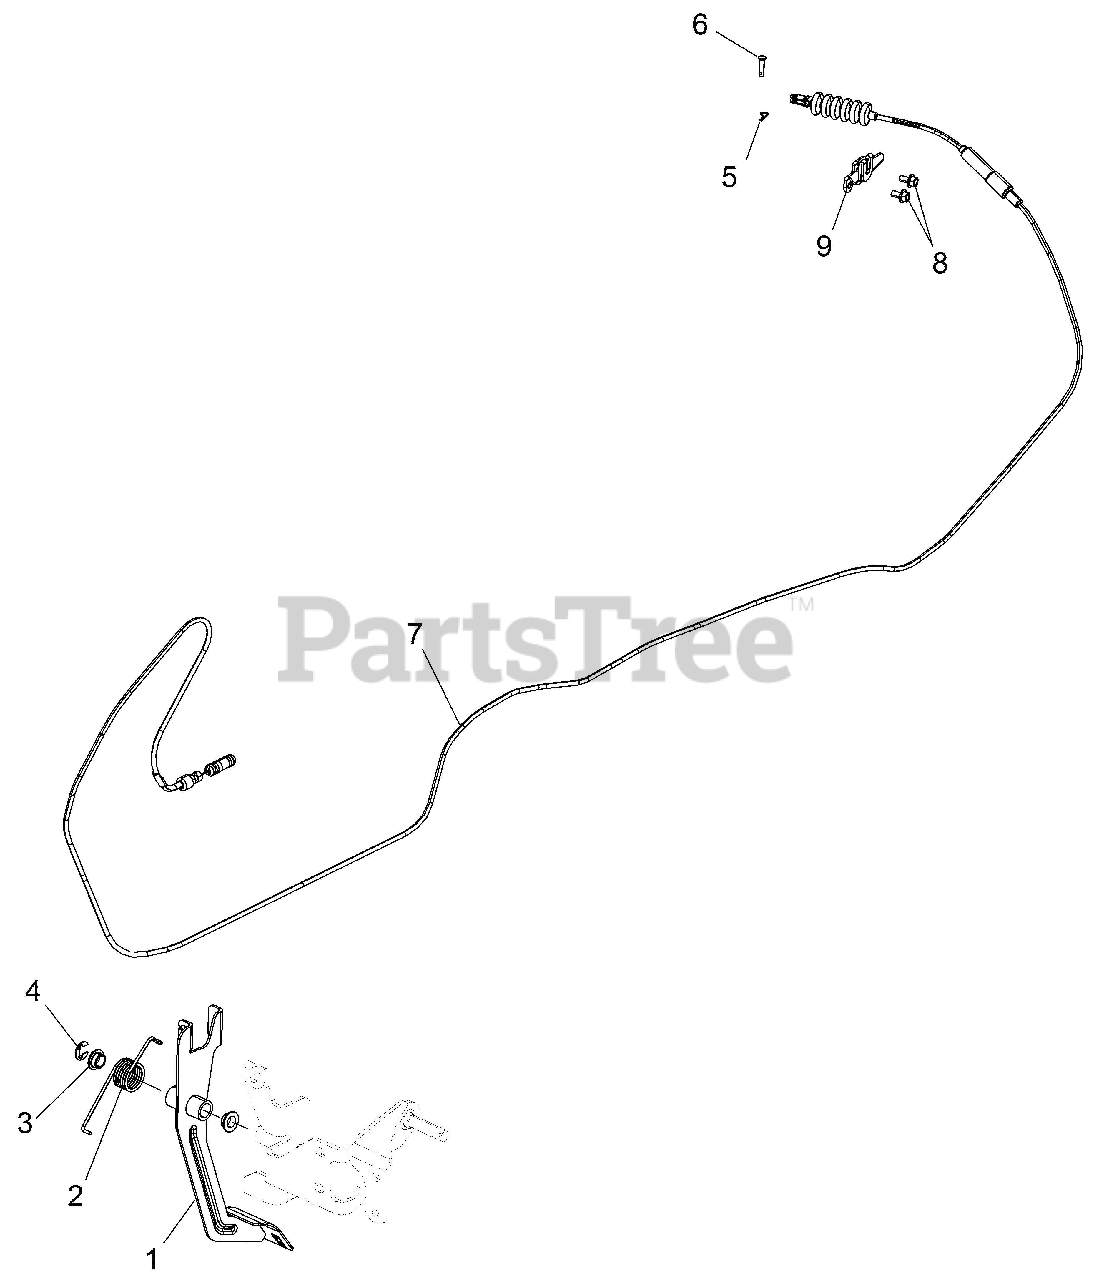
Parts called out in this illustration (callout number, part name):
1	WELD-THROTTLE PEDAL,BLK
2	SPRING-ACCELERATOR,HEAVY
3	BUSHING-PEDAL PIVOT
5	HAIRPIN-COTTER 3/16-1/4
6	PIN,CLEVIS
7	CABLE-THROTTLE,DSL
9	BRKT-THROTTLE,ENGINE
